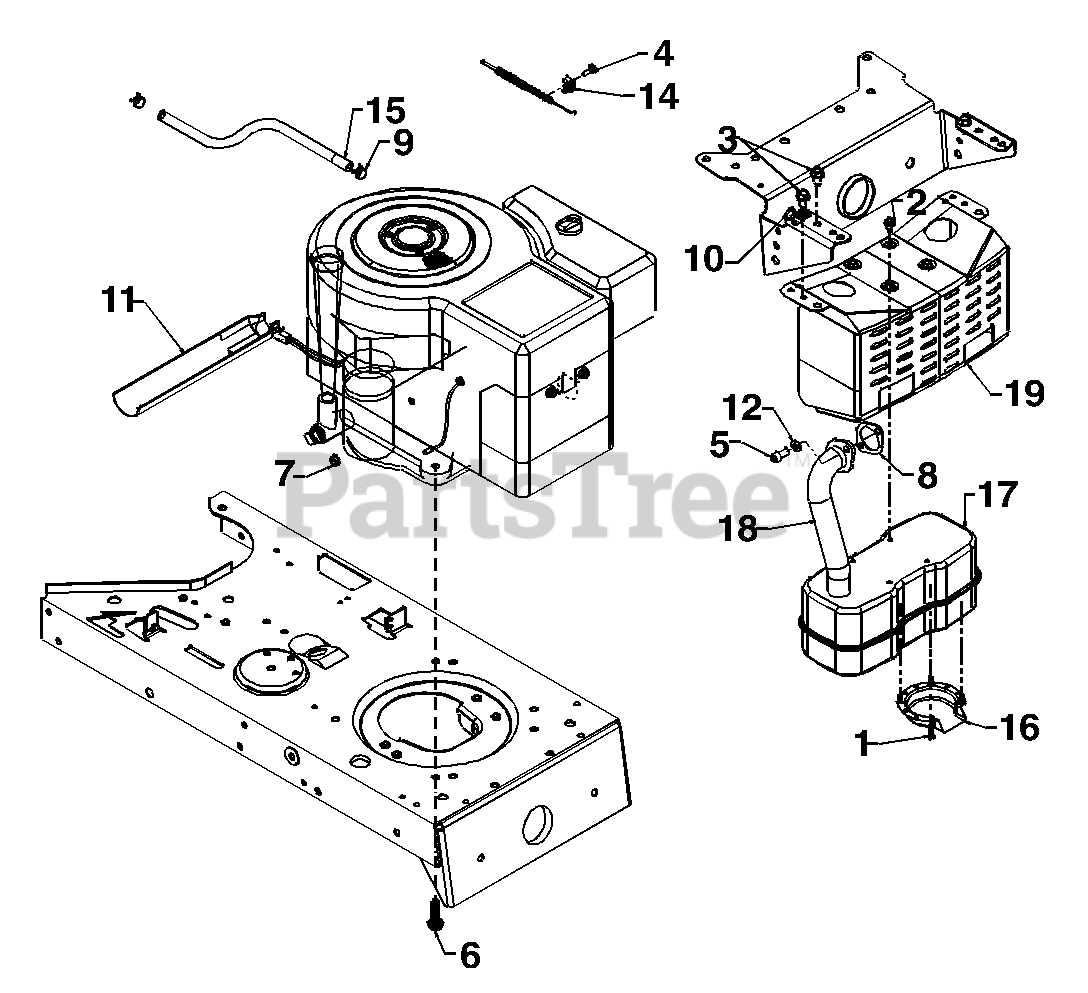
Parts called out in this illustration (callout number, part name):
1	Hex Slot Scr. #8-32 x .38" Lg.
2	Hex Wash. TT-Tap Scr. 1/4-20 .5" Lg.
3	Hex Wash Hd. TT-Tap Scr. 5/16-18 x .62" Lg.
4	Scr. #10-32: .620 Hx. Slot Wash.
5	Socket Hd. Bolt 5/16-18 x .62"
6	Scr. 3/8-16 x 1.25
7	Nut, Hex 1/4-20
8	Exhaust Gasket
9	Hose Clamp .49 Dia.
10	Clamp 9/16 Dia.
11	Oil Drain Sleeve
12	L-Wash. 5/16" I.D.
14	Casing Clamp, Throttle, B&S
15	Fuel Line Hose
16	Muffler Deflector
17	Muffler
18	Exhaust Pipe
